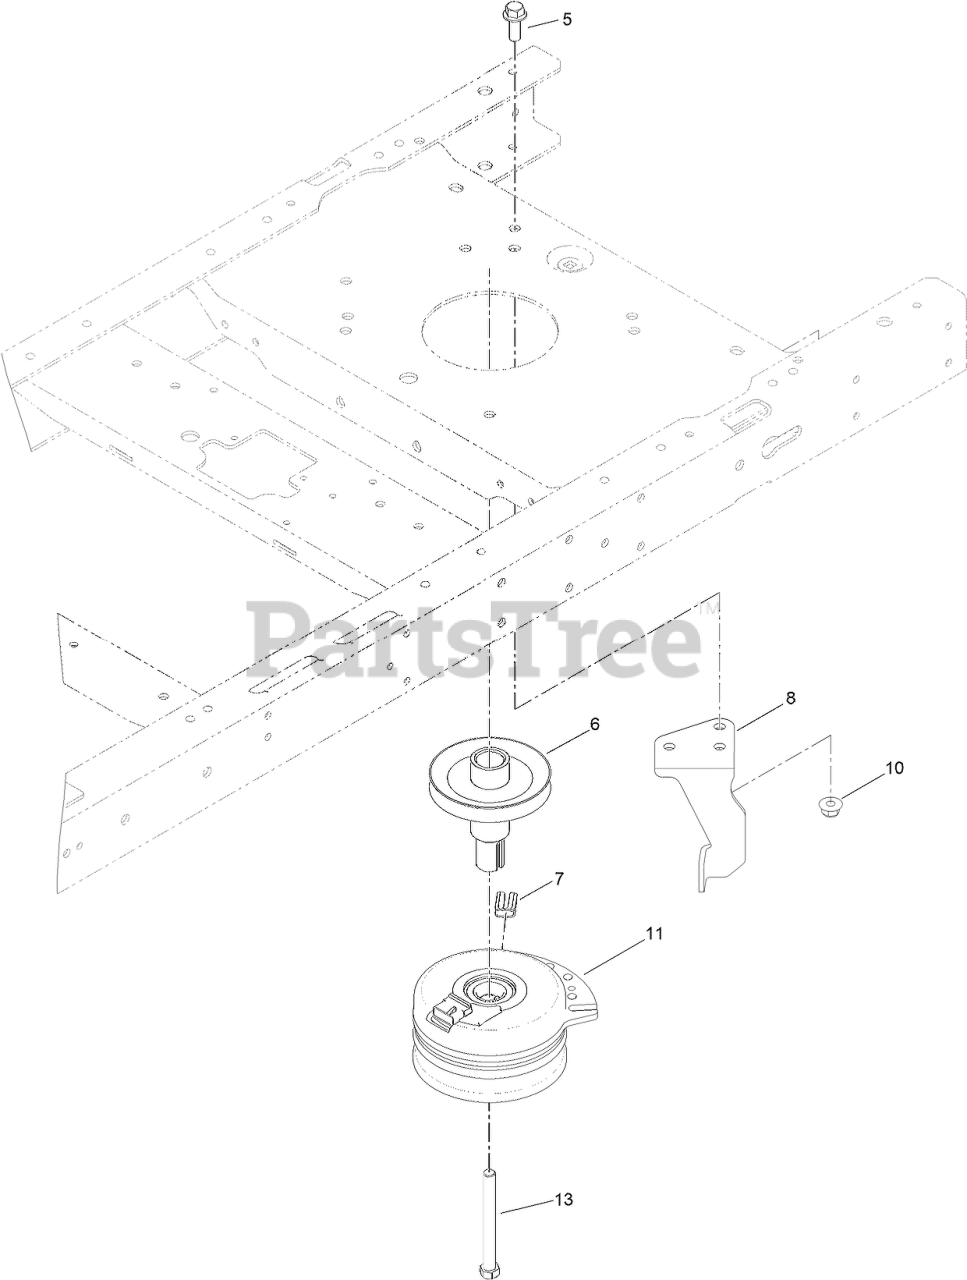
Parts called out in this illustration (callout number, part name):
5	SCREW-HHF
6	PULLEY-ENGINE
7	ISOLATOR-CLUTCH
8	STOP-CLUTCH
10	NUT-HF, NI
11	CLUTCH-ELECTRIC
13	SCREW-HH
